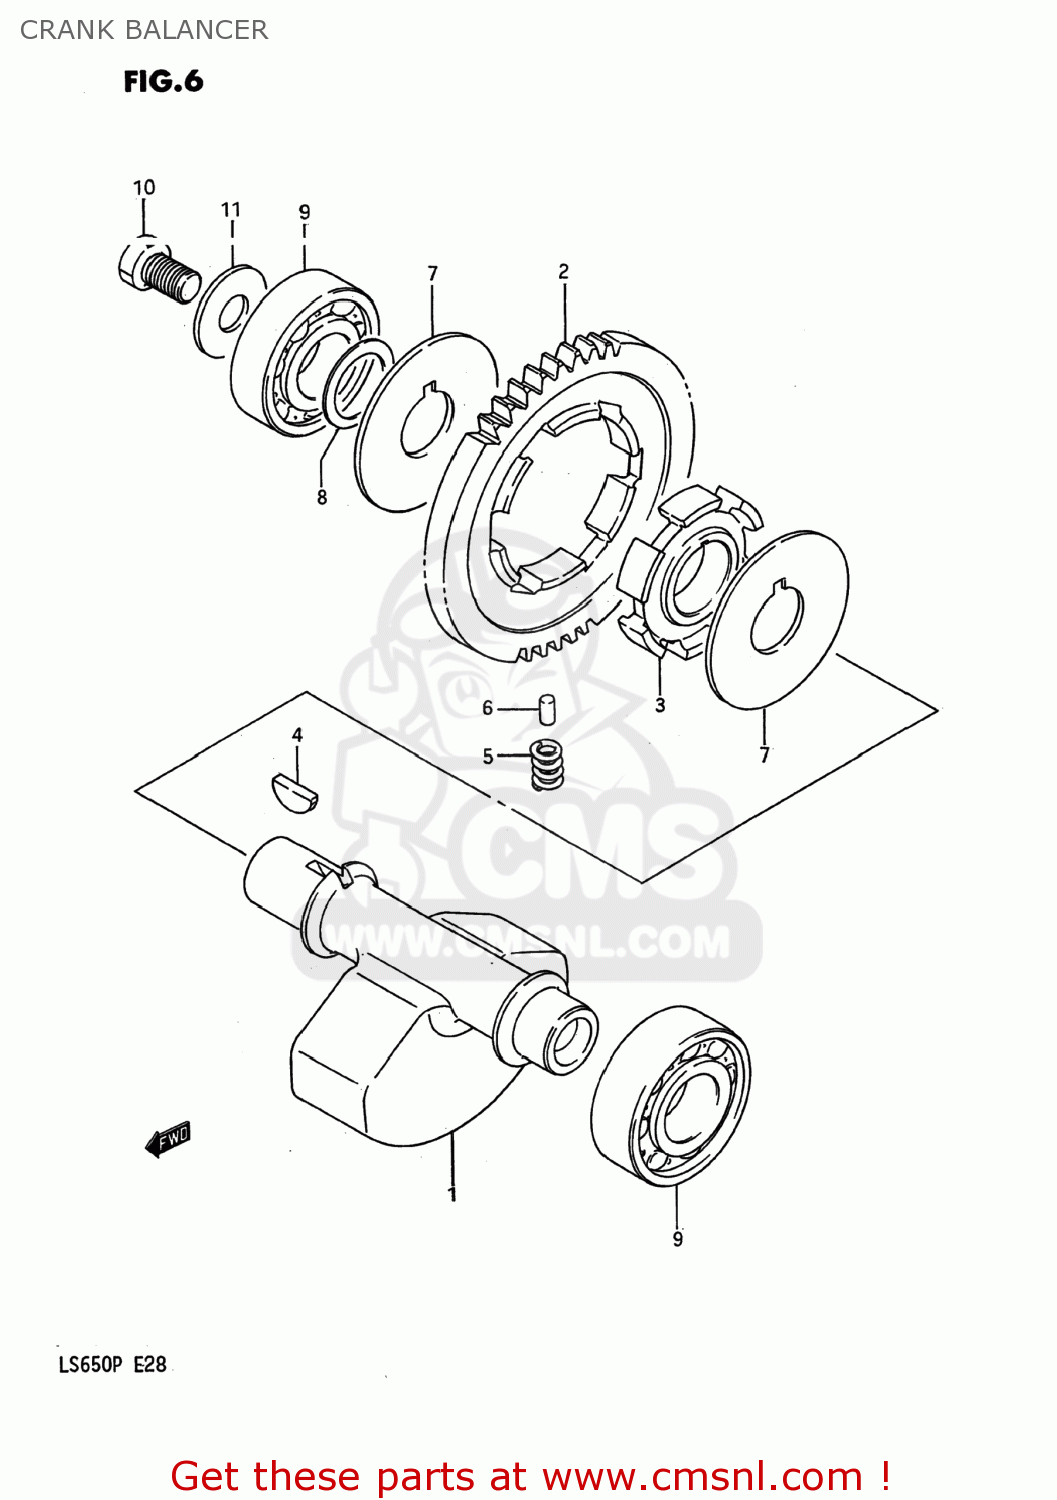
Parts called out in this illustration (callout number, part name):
1	BALANCER,CRANKSHAFT
2	GEAR,CRANK BALANCER
3	RACE,CRANK BALANCER DRIVEN GEAR
4	KEY 4MM
5	SPRING
6	PIN
7	WASHER
8	THRUST WASHER
9	BEARING(20X47X14)
10	BOLT
11	WASHER(10X28X2.2)
